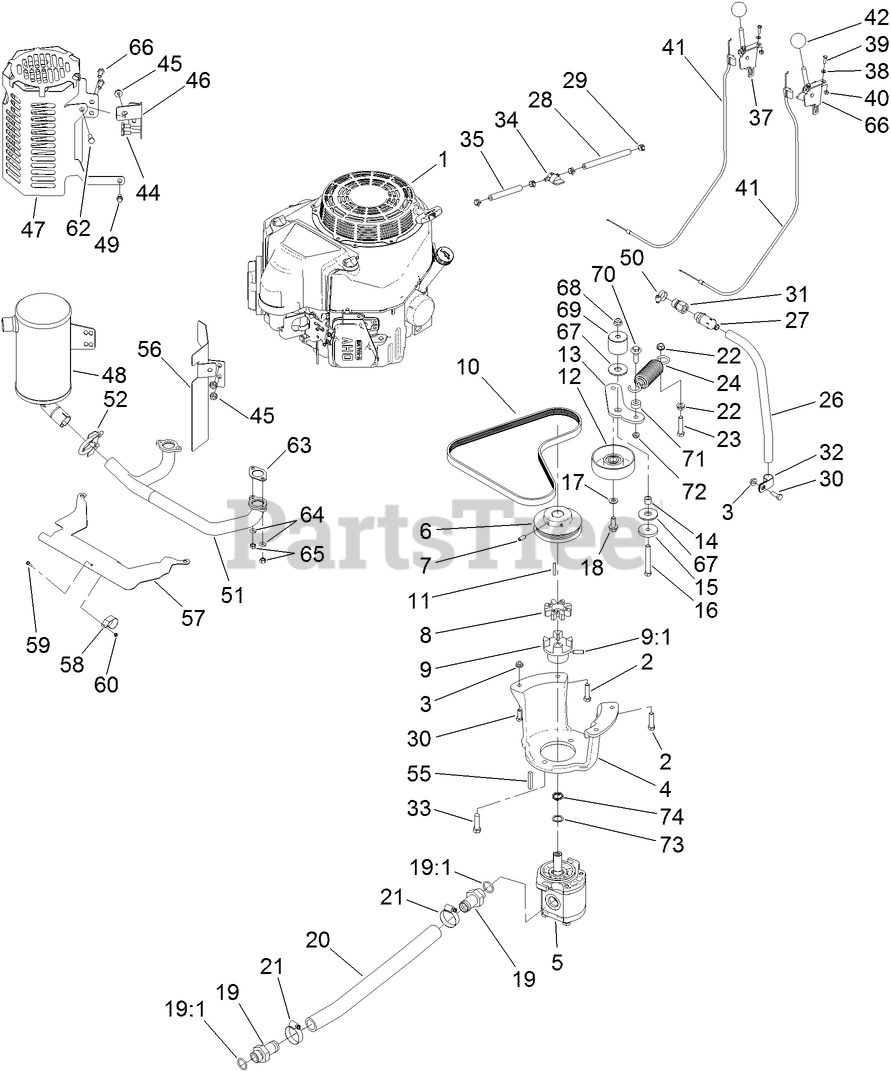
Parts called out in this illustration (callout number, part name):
1	ENGINE-KAWASAKI, FS481V
2	SCREW-HH
3	NUT-HF
4	MOUNT-PUMP
5	GEAR PUMP ASM
6	PULLEY-ENGINE
7	SCREW-SET, HSH
8	COUPLER-SPIDER
9	COUPLER-FLEX
9:1	SCREW-SET
10	BELT-V
11	KEY-SQUARE
12	PULLEY-IDLER
13	ARM-IDLER
14	BUSHING-LEVER, LIFT
15	WASHER-PLAIN
16	SCREW-HH
17	WASHER-FLAT
18	SCREW-HHF
19	FITTING
19:1	O-RING
20	HOSE-SUCTION
22	NUT-HHF, WHIZ
23	SCREW-HH
24	SPRING-EXTENSION
26	HOSE-VENT
27	VALVE-DRAIN, OIL
28	HOSE-FUEL
29	CLAMP-HOSE
30	SCREW-HH
31	Adapter
32	CLAMP-R
33	SCREW-HH
34	VALVE-FUEL
35	HOSE-FUEL
37	LEVER-CONTROL
38	WASHER-FLAT
40	NUT-LOCK, NI
41	CABLE-CONTROL
44	SCREW-HH
45	NUT-HF
46	BRACKET-GUARD, MUFFLER
47	SHIELD-MUFFLER
48	MUFFLER
49	SCREW-HHF
50	CLAMP-HOSE
51	MANIFOLD
52	CLAMP-MUFFLER
55	KEY-SQUARE
56	BRACKET-SHIELD, HEAT
57	PLATE-SHIELD, HEAT
59	SCREW-PAN
60	NUT-HEX
62	SCREW-HH
63	GASKET-EXHAUST
64	WASHER-SPRING
65	NUT-HEX
66	LEVER-CONTROL
67	WASHER-FRICTION, COMPOSITE
68	NUT-HF, NI
69	SPACER-IDLER
70	SCREW-SHOULDER, HWH
71	SPACER
72	NUT-LOCK, NI
73	WASHER-THRUST
74	WASHER-WAVE
